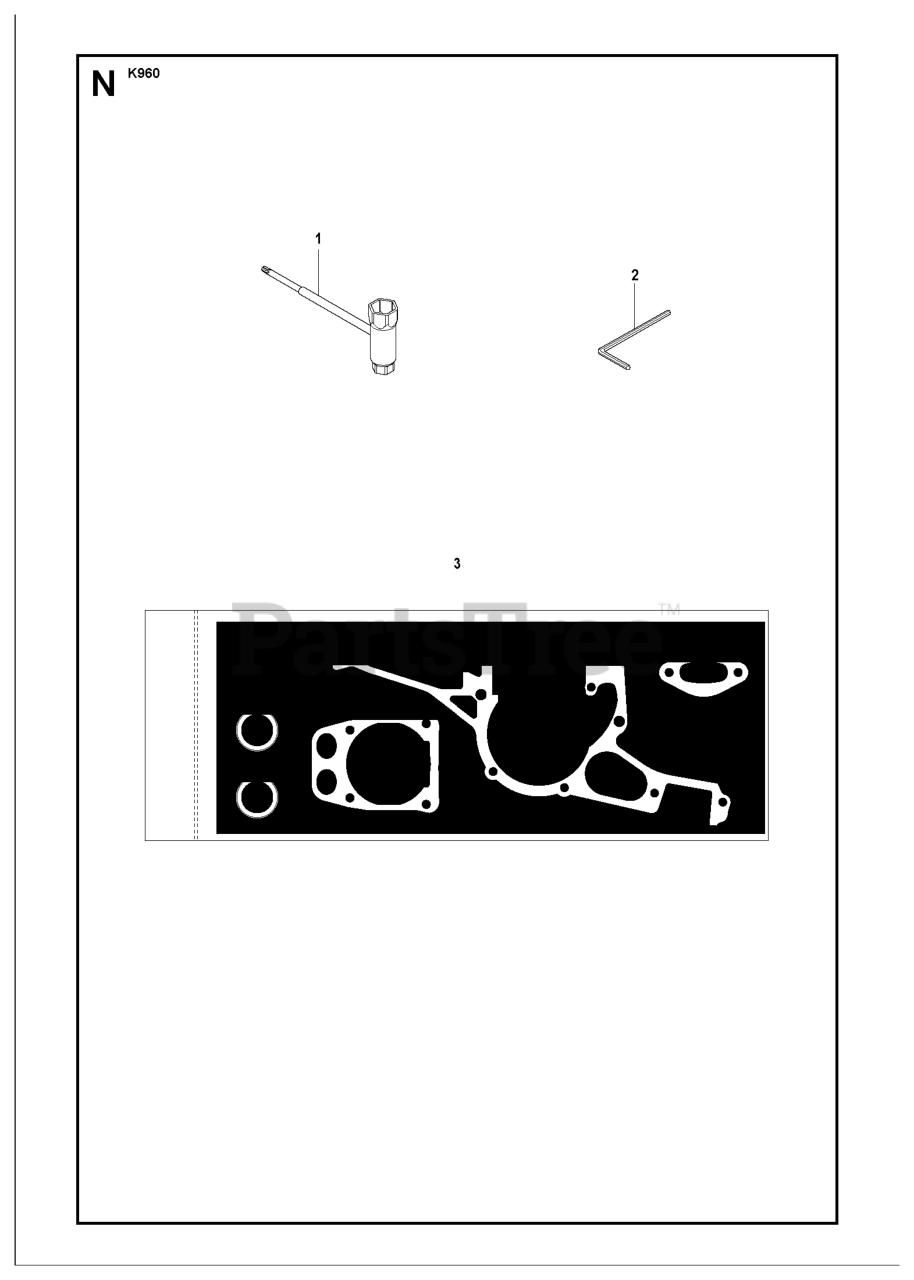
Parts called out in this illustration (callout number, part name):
1	TOOL
2	L-KEY WRENCH
3	RP GASKET KIT
4	SEALING RING
5	RP GASKET
6	RP GASKET
7	GASKET MUFFLER
